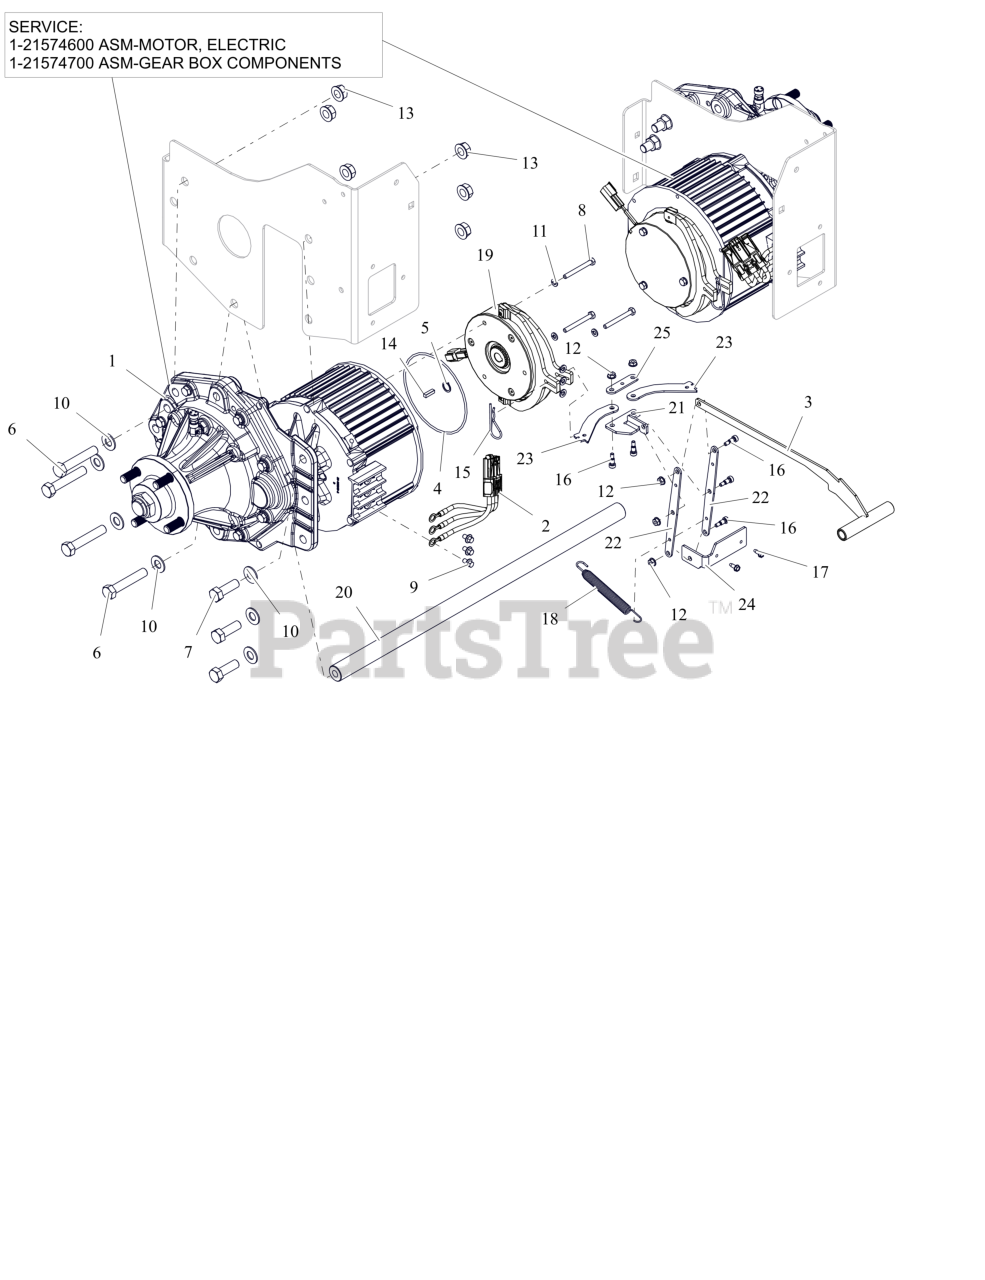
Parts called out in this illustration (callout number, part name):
1	ASM, WHEEL DRIVE
1	ASM-MOTOR, ELECTRIC
1	ASM-GEAR BOX COMPONENTS
2	HARNESS, PHASE - DRIVE MOTOR
3	WLDMT, BRAKE RELEASE
4	O-RING 126MM IDX3MM
5	RING, RETAINING-EXTERNAL 25MM X 1.2MM
6	BLT, HEX .50-13X2.75 G8 ZCC
7	BLT, HEX 0.5-13X1.5 GR8 ZCC
8	BLT-HEX M6-1.00X45 YWZC
9	BLT,HEX M6-1X10 G8.8 ZCC
10	WSHR, FLT .557X1.040X.102 ZCC
11	WSHR,LK-M6 ZCC
12	NUT, FLG-TOP LK #10-24 GRF ZCC
13	NUT, FLG-CTR LK .500-13 GG ZCC
14	KEY-STR 5X5X18MM RD ENDS
15	PIN, HAIR-#7 .094X2.31 ZC120
16	BLT-SHLDR .25X.375
17	SCR,TAP #10-24X.50 HWH TR ZCC
18	SPRING, SWIVEL HOOK EXTENSION
19	BRAKE, MOTOR
20	SHAFT, TRANSAXLE SUPPORT (BLACK)
22	LINK, MIDDLE
23	LINK, PUSH
24	PIVOT, BRAKE LINK MAIN
25	PLATE, BRAKE PULL DOUBLER
